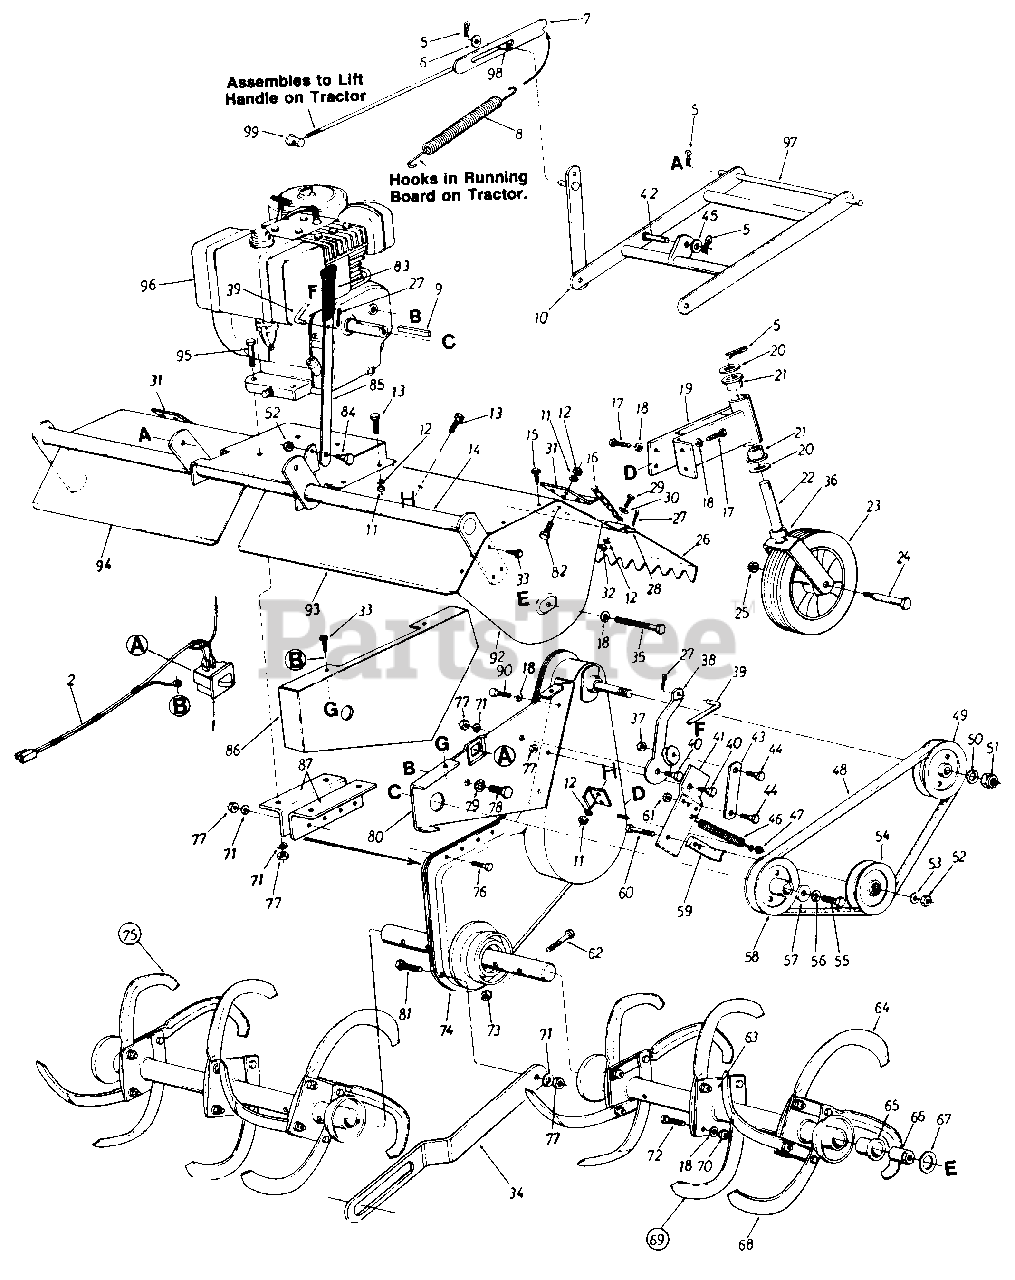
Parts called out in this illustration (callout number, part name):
1	Safety Switch
2	Wire Harness
5	Internal Cotter Pin
6	Fl-Wash. 1/2" I.D. x .93" O.D.
9	Sq. Key 1/4" X 1/4" X 2.00" Lg.
12	L-Wash. 1/4" I.D.
13	Hex Bolt 1/4-28 X .62" Lg.
16	#2 Dog Chain x 20" Lg.
17	Hex Wash. Hd. Self-Tap Scr. 3/8-24 X .75" Lg.
18	L-Wash. 3/8" I.D.
21	Flange Bearing 3/4" I.D. x 1.00" O.D.
24	Shoulder Bolt .623" I.D. x 3.62" Lg.
25	Hex Cent. L-Nut 7/16-14 Thd.
28	L.H Flap Rod
29	Hex Bolt 1/4-20 X .62" Lg.
30	Fl-Wash. 1/4" I.D.
33	Hex Wash. Hd. Self-Tap Scr. 1/4" X.62" Lg
36	Spacer .752" I.D. x 1.25" O.D.
37	Hex Cent. L-Nut 5/16-18 Thd.
40	Shoulder Bolt 7/16" Dia. x 1.75" Lg.
45	Fl-Wash. .50" I.D. x 1.0" O.D. x .06
46	Extension Spring .62" O.D. X 6.12" Lg.
47	Hex Crown Nut 3/8-24 Thd.
48	"V"-Belt (Kevlar)
49	1/2" "V"-Pulley 4.75" O.D. x .625" Bore
50	L-Wash. 5/8" I.D.
51	Hex Ins. L-Nut 5/8-18 Thd.
52	Hex Cent. L-Nut 3/8-16 Thd.
53	Fl-Wash. 3/8" I.D.
54	Idler Pulley 4.0" O.D.
55	Hex Bolt
56	L-Wash. 7/16" I.D.
57	Fl-Wash. 7/16" I.D. x 1.38"
58	1/2" "V"-Pulley .475" O.D. x 1.00" Bore
61	Hex Cent. L-Nut 5/16-18 Thd.
62	Hex Bolt 7/16-14 x 2.00" Lg.
66	Spacer
67	Thrust Wash. 1/2" I.D. x 1.55"
71	L-Wash. 5/16" I.D.
72	Hex Bolt 3/8-24 x 1.5" Lg.
73	Hex Cent. L-Nut 7/16-14 Thd.
77	Hex Nut 5/16-18 Thd.
78	Hex Bolt 5/16-24 x . 62" Lg.
79	L-Wash. 1/2 " I.D.
80	Clutch Support Bracket
81	Shld. Bolt .435 Dia. x .265 5/16-18 Thd.
82	Hex Bolt 1/4-28 x .75" Lg.
83	Plastic Grip
84	Shoulder Bolt .498 Dia. x .212 Lg.
96	8 H.P. Engine
97	Hitch Rod
98	Push Bar Sleeve .503" I.D. x .624" O.D.
99	Ferrule
